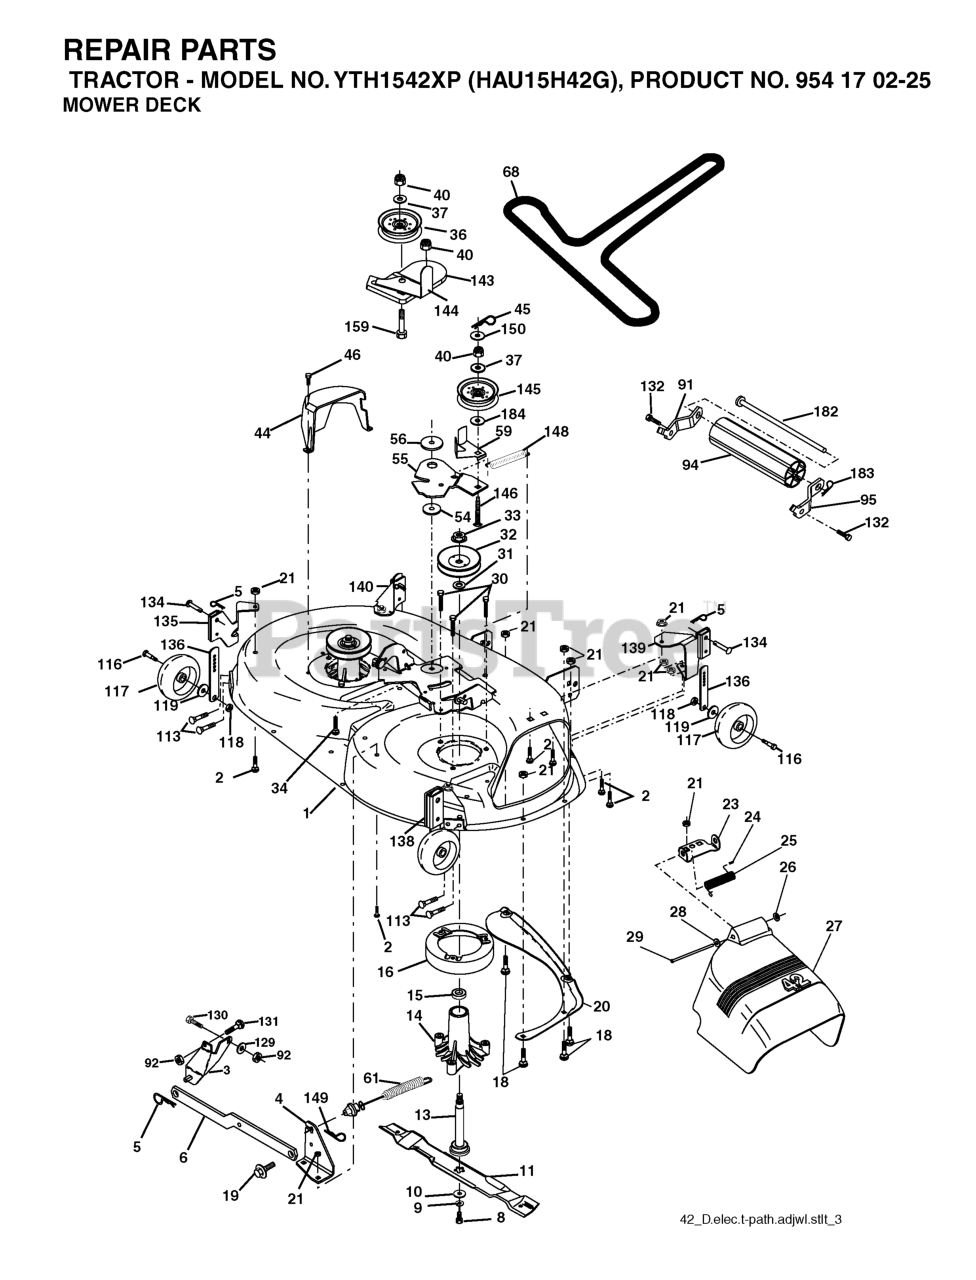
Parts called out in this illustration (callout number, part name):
1	MOWER DECK SHELL 42"
2	RP BOLT 5/16-18 X3/4 ZN/YEL GR
3	BRKT ASM SWAY BAR
4	BRACKET SWAY BAR 42" DECK
5	RETAINER-SPRNG RB
6	BAR SWAY DECK
8	BLADE BOLT
9	LOCKWASHER
10	WASHER.BLADE
11	42" HI-LIFT BLADE
13	SHAFT ASM VENT
14	HOUSING.MANDREL.VENTED (MACHD)
16	STRIPPER.MANDREL.ROUND.BLACK
18	BOLT
19	BOLT SHD 5/16-18
20	BAFFLE.VORTEX
21	LOCKNUT
23	BRKT, DEFL. MOWER
24	CAP-SLEEVE LT
25	SPRING TORSION
26	NUT PUSH M
27	SHIELD DEFLECTOR
28	Washer 11/32 x 5/8 x 16 Ga SD
29	ROD.HINGE
30	SCREW, WASHER HEAD
31	WASHER.SPACER.MANDREL
32	PULLEY MANDREL
33	NUT, FLG TOPLOCK 9/16"
34	BOLT.3/8-16X1.50
36	PULLEY.IDLER.FLAT
40	NUT LOCK FLG 3/8-16 UNC
44	GUARD MANDREL LH BLACK
45	RETAINER M
46	SCREW.1/4-20X5/8
55	ARM IDLER 42" MOWER LT/YT
56	SPACER RETAINER
59	GUARD TUV IDLER
61	SPRING EXT ELEC CLUTCH
68	V-BELT PRIMARY 42"
91	BRACKET ASM NOSEROLLER LH
92	NUT
94	NOSE ROLLER
95	BRACKET ASM NOSEROLLER RH
113	SCREW 5/16"
116	SHOULDER BOLT
117	WHEEL GAGE DONUT
118	LOCKNUT
119	WASHER.5/16.FLAT.STE.STD.
129	WASHER
130	BOLT
131	BOLT D
132	SCREW, 3/8-16X3/4
134	RIVET.PIN.HEAD.YELLOW.
135	BRACKET ASM, WHEEL
136	BAR.ADJUST.WHEEL.ANTI.SCALP.BL
138	BRACKET.ASM.WHL.GA.R.RH.42".GR
139	BRACKET ASM, WHEEL
140	BRACKET ASM, WHEEL
143	BRACKET, ARM IDLER
144	KEEPER BELT 42" CLUTCH
145	PULLEY.IDLER.FLAT.PLATED
146	BOLT CARRIAGE IDLER
148	IDLER RETURN SPRING
149	SPRING.RETAINER.YELLOW.ZINC
150	WASHER LT
159	BOLT
182	ROD ROLLER NOSE STANDARD
183	SPRING RETAINER
184	WASHER
